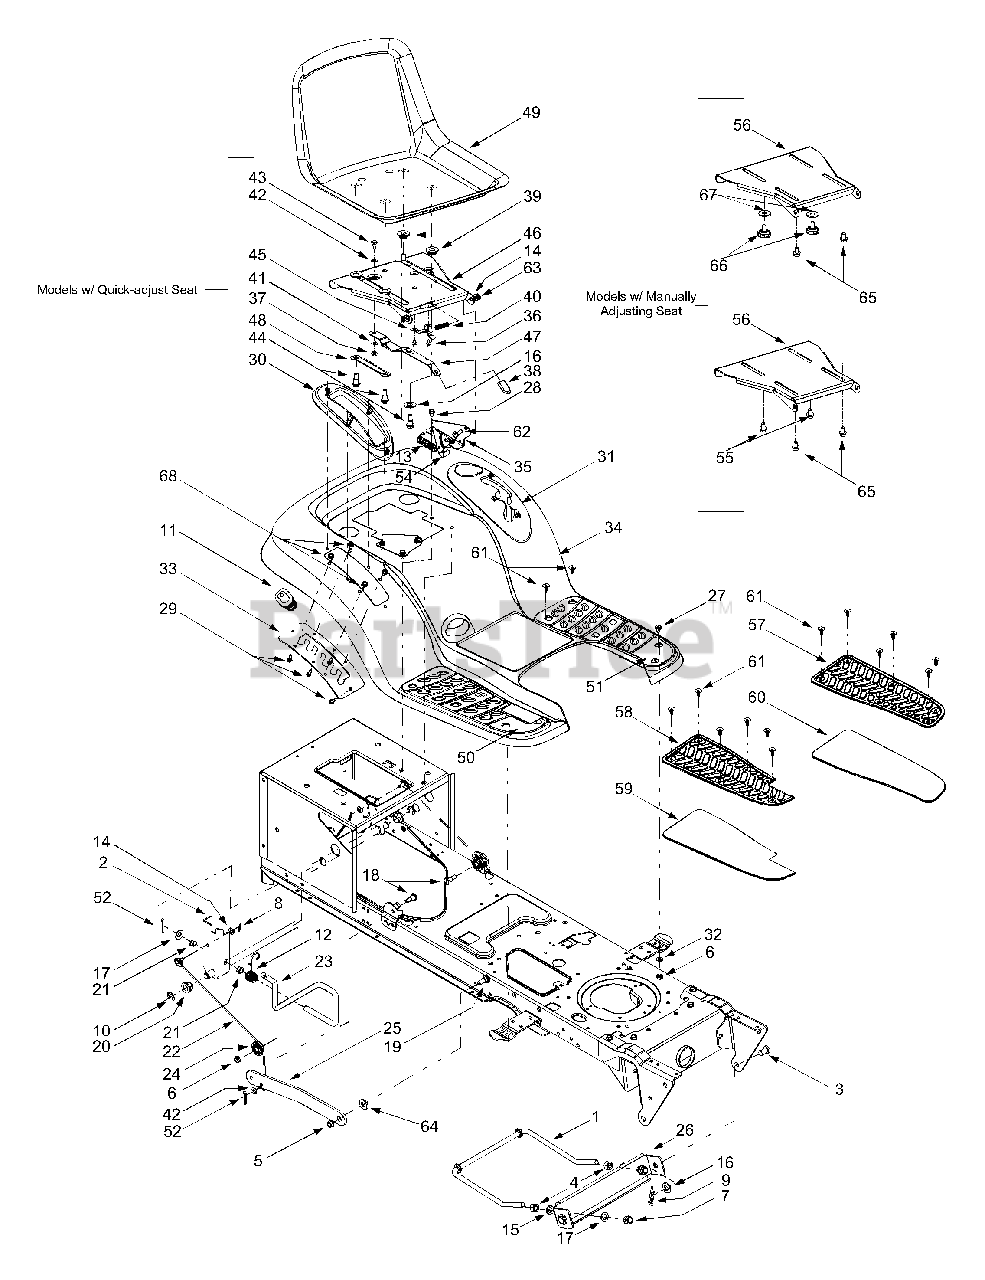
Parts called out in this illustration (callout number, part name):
1	Deck Stabilizer Rod
3	Clevis Pin,.5 x.78
4	Hex Nut, 1/2-13
5	Flange Lock Nut, 3/8-16
6	Flange Lock Nut, 5/16-18
7	Hex Nut, 1/2-13
8	Internal Cotter Pin
9	Internal Cotter Pin
10	E-ring
11	Handle Grip
12	Torsion Spring
13	Extension Spring,.84 x 4.6
14	Flat Washer, 5/16
15	Lock Washer, 1/2
16	Flat Washer,.31 x 1.062 x.134
17	Flat Washer,.51 x 1.12 x.06
18	Hex Cap Screw, 5/16-18 x.62
19	Shoulder Screw, 3/8-16
20	Hex Flange Bearing
21	Snap Flange Bearing
22	Lift Cable, 16.16 (42" Decks)
22	Lift Cable, 15.62 (46" Decks)
23	Lift Handle
24	Roller Pulley
27	Carriage Bolt, 5/16 x.62
28	Self-tapping Screw, 5/16-18 x.625
29	Self-tapping Screw, 1/4-15 x.75
30	Lift Lever Cover
31	Shift Lever Cover w/ Cup Holder
32	Flat Washer,.349 x 1.0 x.063
36	Screw, #10-16 x.375
37	Hex Flange Lock Nut, 1/4-20
38	Seat Adjuster Grip
39	Spacer
40	Compression Spring,.41 x 1.5
41	Spring Washer,.265 x.562 x.025
42	Flat Washer,.344 x.62 x.03
43	Shoulder Screw,.340 x.285,1/4-20
44	Shoulder Screw,.50 x.50, 3/8-16
45	Seat Stop
48	Seat Adjustment Selector
49	High Back Seat, Black
49	High Back Seat w/ Drain Holes, Black
49	Medium Back Seat, Black
50	RH Foot Pad, Rubber (4-Style Fender)
51	LH Foot Pad, Rubber (4-Style Fender)
52	Cotter Pin
54	Seat Lift Bracket
55	Hex Head Washer Screw, 3/8-16 x.625
57	RH Foot Pad, Rubber (7-Style Fender)
58	LH Foot Pad, Rubber (7-Style Fender)
59	RH Foot Pad, Grit (7-Style Fender)
60	LH Foot Pad, Grit (7-Style Fender)
61	Ratchet Clip
62	Shoulder Screw,.437 x.286
63	Speed Nut,.3125
64	Flat Washer,.531 x.93
65	Shoulder Spacer
66	Knob, 3/8-16
67	Cupped Washer,.39 x 1.12
68	Self-tapping Screw, 5/16-18 x.75
